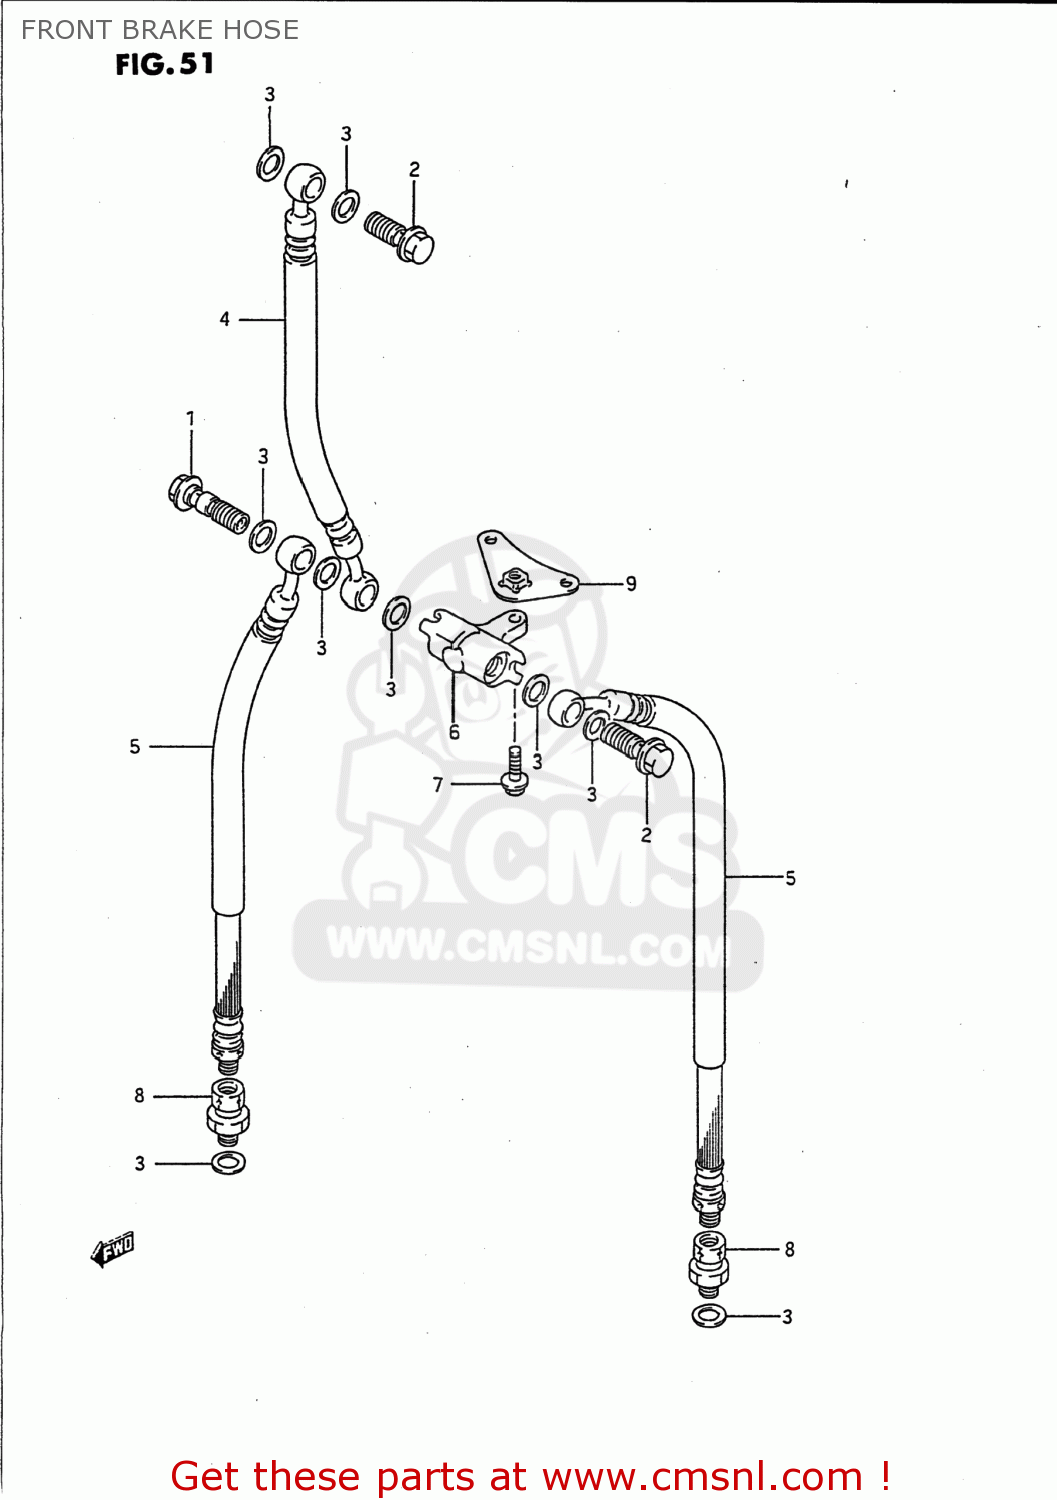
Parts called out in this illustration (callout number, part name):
1	BOLT UNION
2	BOLT UNION
3	WASHER(10X15X1.5)
4	HOSE,FR BRAKE NO.1
5	HOSE,FR BRAKE NO.2
6	JOINT,BRAKE HOSE
7	BOLT
8	ADAPTER,BRAKE HOSE
9	PLATE,FRONT BRAKE JOINT
